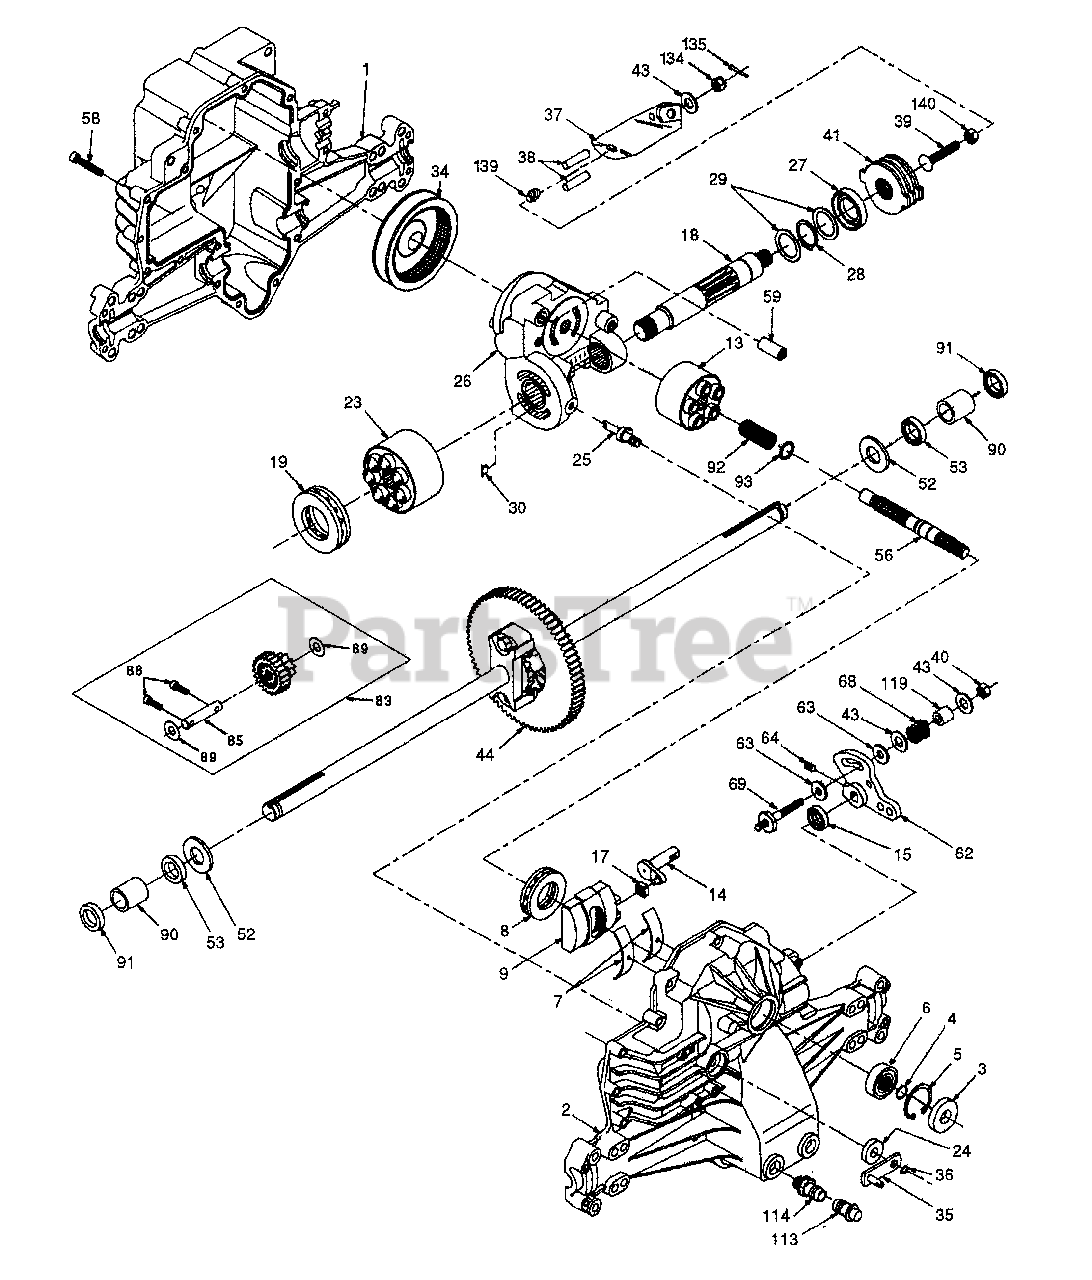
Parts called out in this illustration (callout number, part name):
1	Housing, Lower
2	Assembly, Upper Housing
4	,Ring, Wire Retaining
5	Ring, Retaining
6	Bearing, Shaft Ball
7	Bearing, Cradle
8	Bearing, Thrust 30 x 52 x 13
9	Swashplate, Variable
13	Block, Cylinder Assembly
14	Arm, Trunnion
17	Guide, Slot
18	Shaft, Motor
19	Bearing, Thrust 42 x 68 x 16
23	Block, Cylinder Assembly
24	Seal, Lip 10 x 25 x 7
25	Actuator, Bypass
26	Center Section Assembly Kit
27	Seal, Lip 26 x 42 x 8
28	Ring, Retaining
29	Washer 26 x 35 x 1
34	Oil Filter Element
35	Arm, Bypass
36	Ring, Retaining
37	Arm, Actuating
38	Pin, Actuating
39	Bolt 5/16-24 x 1-3/4
40	Locknut, Hex 5/16-24 UNJC
41	Brake Rotor/Stator Kit
43	Washer 7/16 x 7/8 x .060
44	Differential Assembly
52	Washer 3/4 x 1.5 x .13
53	Seal .75 x 1.25 x .250
56	Shaft, Input
58	Bolt 1 /4-20 x 1.38
59	Pin .5 OD x .43 ID x .750
62	Arm, Control
63	Puck, Dampener
69	Stud 5/16-24
83	Jackshaft Assembly
88	Screw, Cap
89	Washer 7/16 x 1 x 1 /2
90	Sleeve Bearing
91	Seal, Wiper
92	Spring, Block
93	Washer, Block Thrust
113	Cap, Vent Assembly
114	Fitting, O-Ring Assembly
119	Spacer
134	Nut, Castle 5/16-24
135	Pin, Cotter
139	Spring, Compression
140	Nut, Hex 5/16-24
